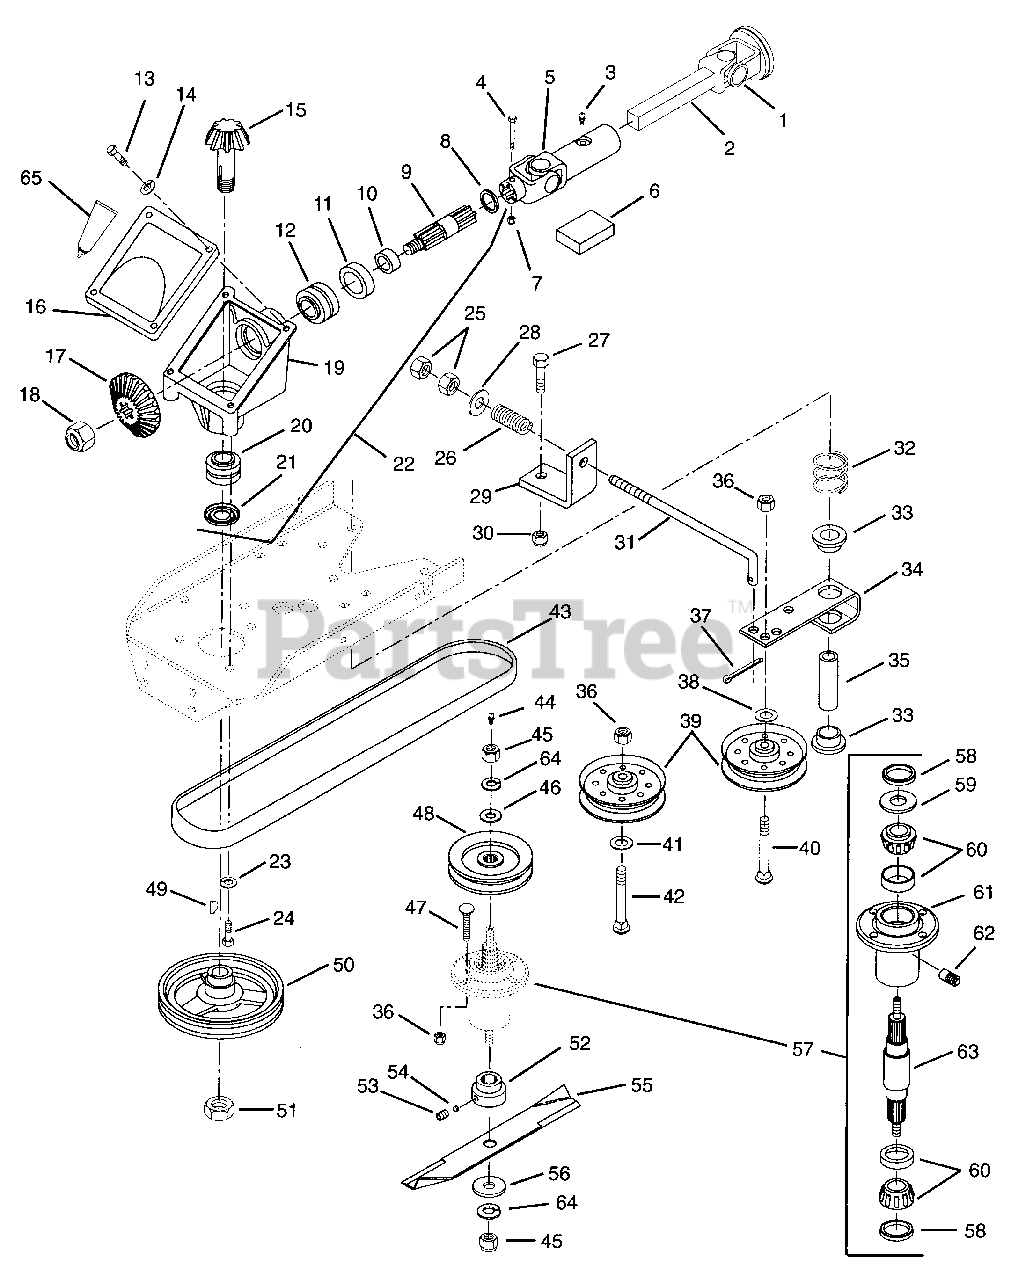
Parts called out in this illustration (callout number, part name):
1	Yoke, Quick Disconnect
1	Spring
1	Collar
1	Ring, Snap
1	Ball .375 Guard
2	Shaft, Prop Square Bar
3	Fitting-Lube .25-28 x .256
4	Bolt-Hex .25-20 x 2.00 Grade 5
5	U-Joint, Female End
5	Kit, Repair, U-Joint
6	Kit, Repair, Journal Cross and Bearing Assembly
7	Nut-Locking-Nylon .250-20 Grade 2
8	Ring-Retaining 1.106 x .95
9	Shaft
10	Bushing Flange 1.00 x 1.25 x 1.25
11	Seal 1.250 x 1.983 x .250
12	Bearing-Assembly 1.000 x 1.980 x 1.243
13	Bolt-Hex .25-20 x .50 Grade 5
14	Washer-Lock .250 Reg.
15	Shaft, Pinion Gear
16	Cover, Gear Housing
17	Gear, Bevel
18	Nut-Locking-Nylon .75-10 Grade 2
19	Casting, Gear Box
20	Bearing-Assembly .75 x 1.781 x 1.499
21	Seal 1.250 x 1.691 x .310
22	Assembly, Gear Box
23	Washer-Lock .50 Reg.
24	Bolt-Hex .50-13 x 1 Grade 5
25	Nut-Hex .375-24 Grade 2
26	Spring-Compression .125 x .78 x 1.00
27	Bolt-Hex .50-13 x 1.375
28	Washer-Flat-Steel .406 x .812 x .065
29	Support, Spring
30	Nut-Locking-Nylon .50-13 Grade 5
31	Rod, Idler 50 In. Mower
32	Spring-Compression .085 x .80 x 1.00
33	Bushing-Flange .762 x 1.0 x .580 x 1.48
34	Arm, Idler Pivot
35	Spacer .560 x .750 x 2.437
36	Nut-Locking-Nylon .375-16 Grade 2
37	Pin-Cotter .09 x 1.0
38	Bushing .406 x .750 x .188
39	Pulley-Idler 4.50 x .380
40	Bolt-Hex .38-16 x 3.00 Grade 5
41	Washer-Flat-Steel .438 x 1.000 x .083
42	Bolt-Round Head Square Neck .38-16 x 1.75
43	Belt, V .5 x .312 x 126.3
44	Fitting-Lube 1/8 (Left and Right Spindle)
44	Fitting-Lube .125 (Center Spindle)
45	Nut, Hex .625-11 Grade 2
46	Washer-Flat-Steel .687 x 1.312 x .150
47	Bolt-Round Head Square Neck .38-16 x 1.25
48	Sheave
49	Key-Woodruff .19 x .63
50	Sheave, 1/2 x 6.50
51	Nut-Hex-Jam .750-10
53	Screw-Set, Socket Head Cup Point .25-20 x .25
55	Blade
56	Washer-Flat .640 x 1.81 x .250
57	Service Kit Spindle Assembly
58	Seal 1.987 x 1.375 x .313
59	Washer, Hardened Thrust 1.007 x 1.1542 x .062
60	Assembly, Bearing Cup & Cone
61	Bearing Housing
62	Relief Fitting, Grease
63	Shaft, Spindle
64	Washer, Locking .625 x .156
65	Kit, Liquid Gasket
